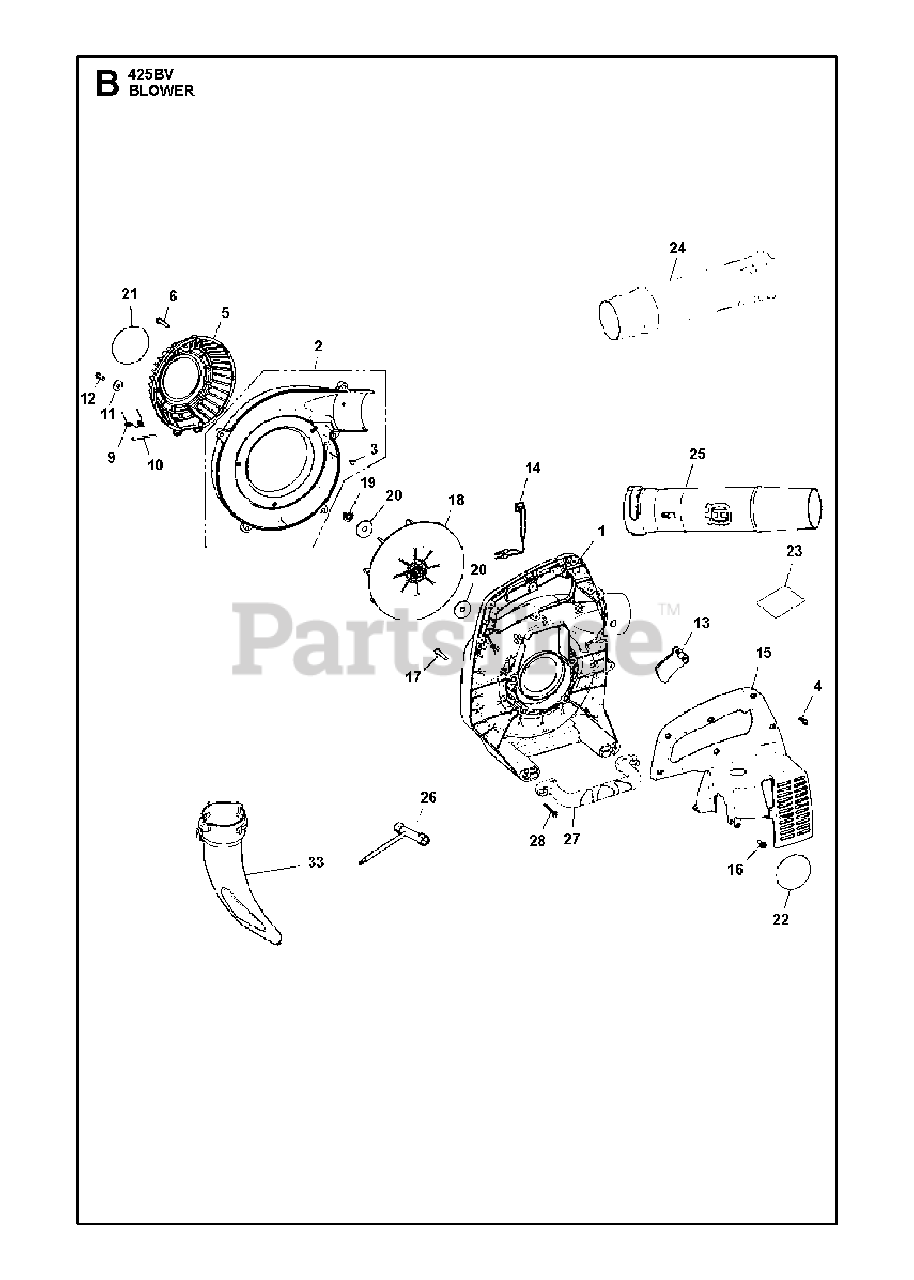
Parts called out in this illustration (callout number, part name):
3	SCREW
4	SCREW, TORX (RPLS T4970-52001)
19	NUT
33	FLAT NOZZLE
